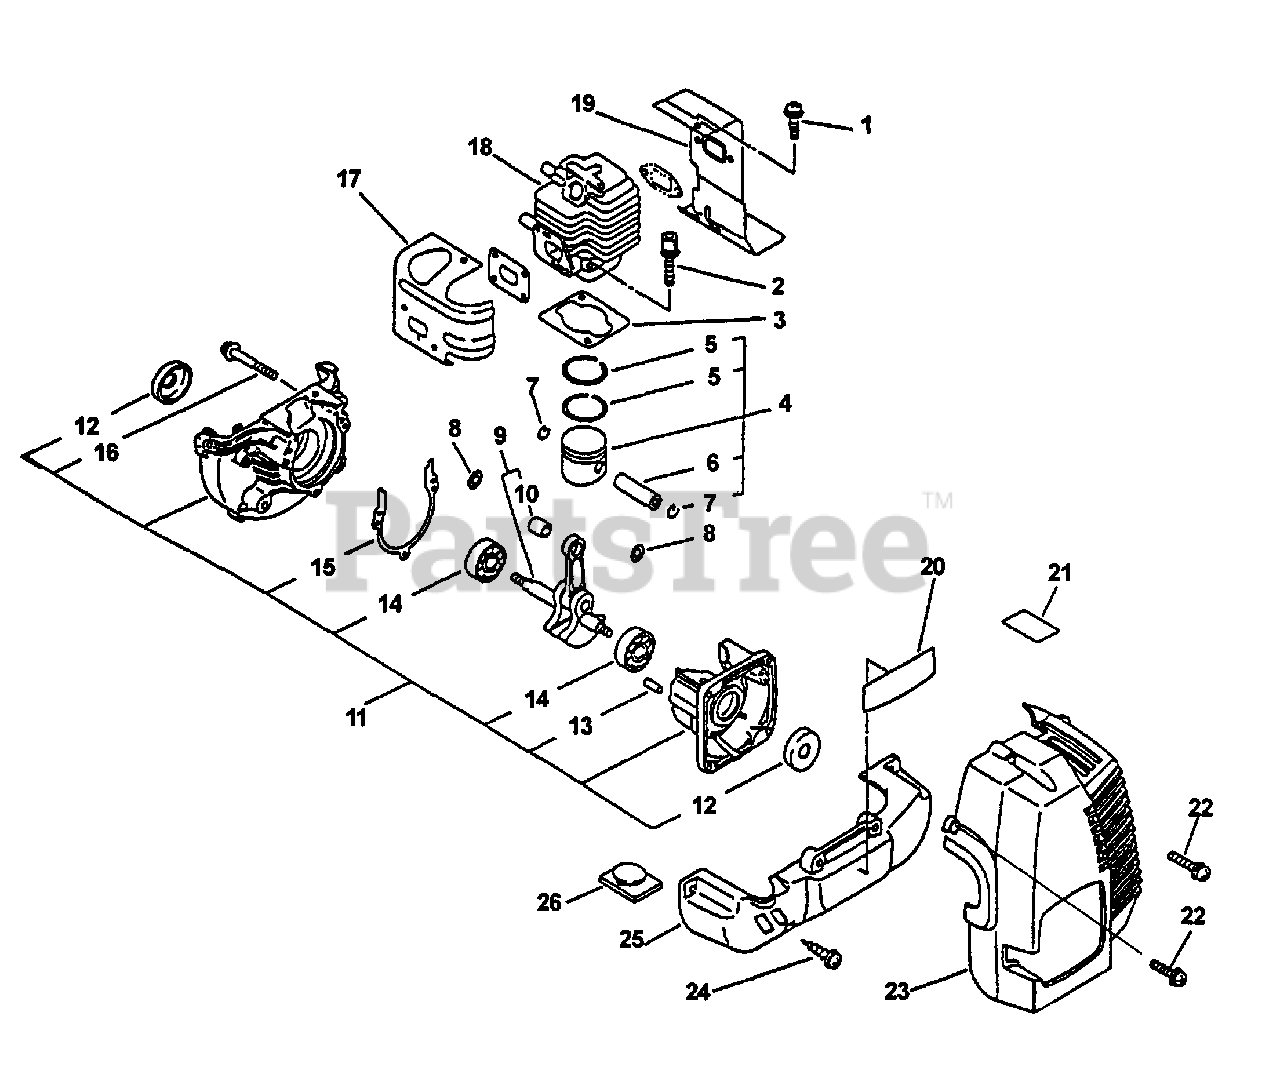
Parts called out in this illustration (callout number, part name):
1	SCREW 5×10
2	BOLT 5×22
3	GASKET, CYLINDER
4	PISTON KIT
5	RING, PISTON
6	PIN, PISTON 8
7	RING, SNAP
8	WASHER, THRUST
9	CRANKSHAFT ASSY
10	BEARING, NEEDLE
11	CRANKCASE KIT
12	SEAL, OIL 12
13	PIN, LOCATING 4
14	BEARING, BALL - 6201 C3
15	GASKET, CRANKCASE
16	BOLT 5×28
17	COVER, CYLINDER
18	CYLINDER
19	COVER, CYLINDER
20	LABEL - MODEL
21	LABEL - CAUTION -- HOT
22	SCREW 5×16
23	COVER, ENGINE
24	SCREW, TAPPING 5×20
